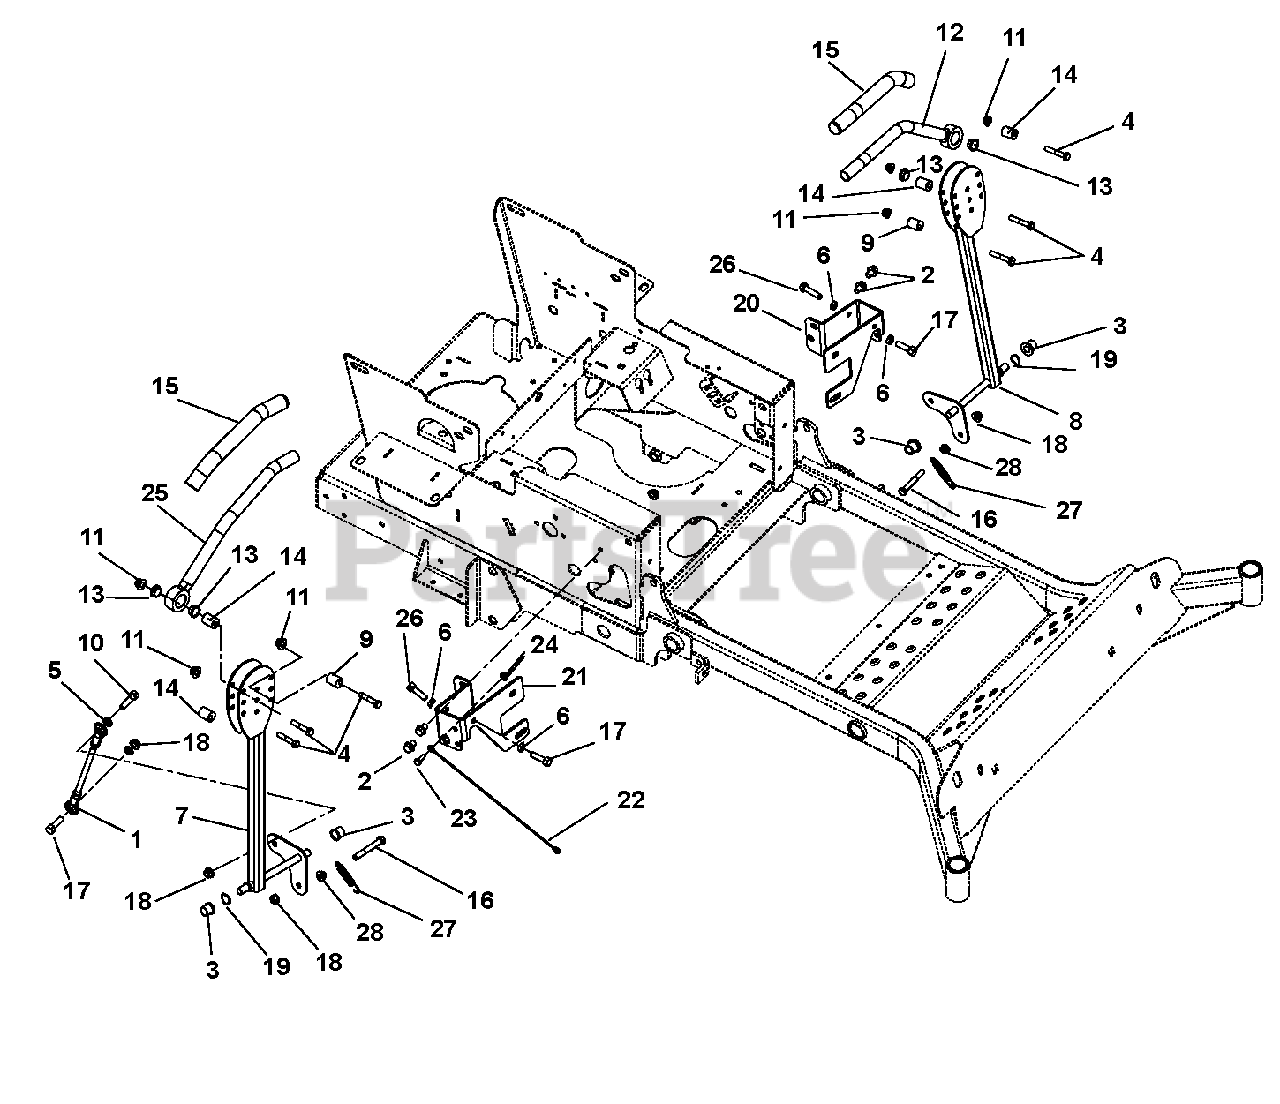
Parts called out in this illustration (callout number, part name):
1	Assembly, Steering Linkage
2	Screw, Tapping .38-16 x .50 Hex Washer Head
3	Bushing, Flange .515 x .750 x .745 x 1.00 Nylon
4	Bolt, Hex .31-18 x 1.75 Grade 5
5	Washer, Locking .38 x .094
6	Nut, Hex Jam .375-16
7	Weldment, Right Hand Control Arm
8	Weldment, Left Hand Control Arm
9	Eccentric
10	Bolt, Hex .38-16 x 1.50 Grade 5
11	Nut, Nyloc Flange .375-16
12	Handle Weldment, Left Hand
13	Bushing, Flange Nylon .762 x 1.48 x .44
15	Grip, Handlebar
16	Bolt, Hex .38-16 x 2.75 Grade 5
17	Bolt, Hex .38-16 x 1.25 Grade 5
18	Nut, Nyloc Flange 3/8-16
19	Wave Washer
20	Stop, Steering, Left Hand
21	Stop, Steering, Right Hand
22	Cable, 12.0 Lanyard, Nylon
23	Bolt, Hex .25-20 x .75 Grade 5
24	Nut, Nyloc Flange .25-20
25	Handle Weldment Right Hand
26	Bolt, Hex .38-16 x .75 Grade 5
27	Spring, External, .061 x .50 x 3.0
28	Nut, Spin Lock Flange .375-16
